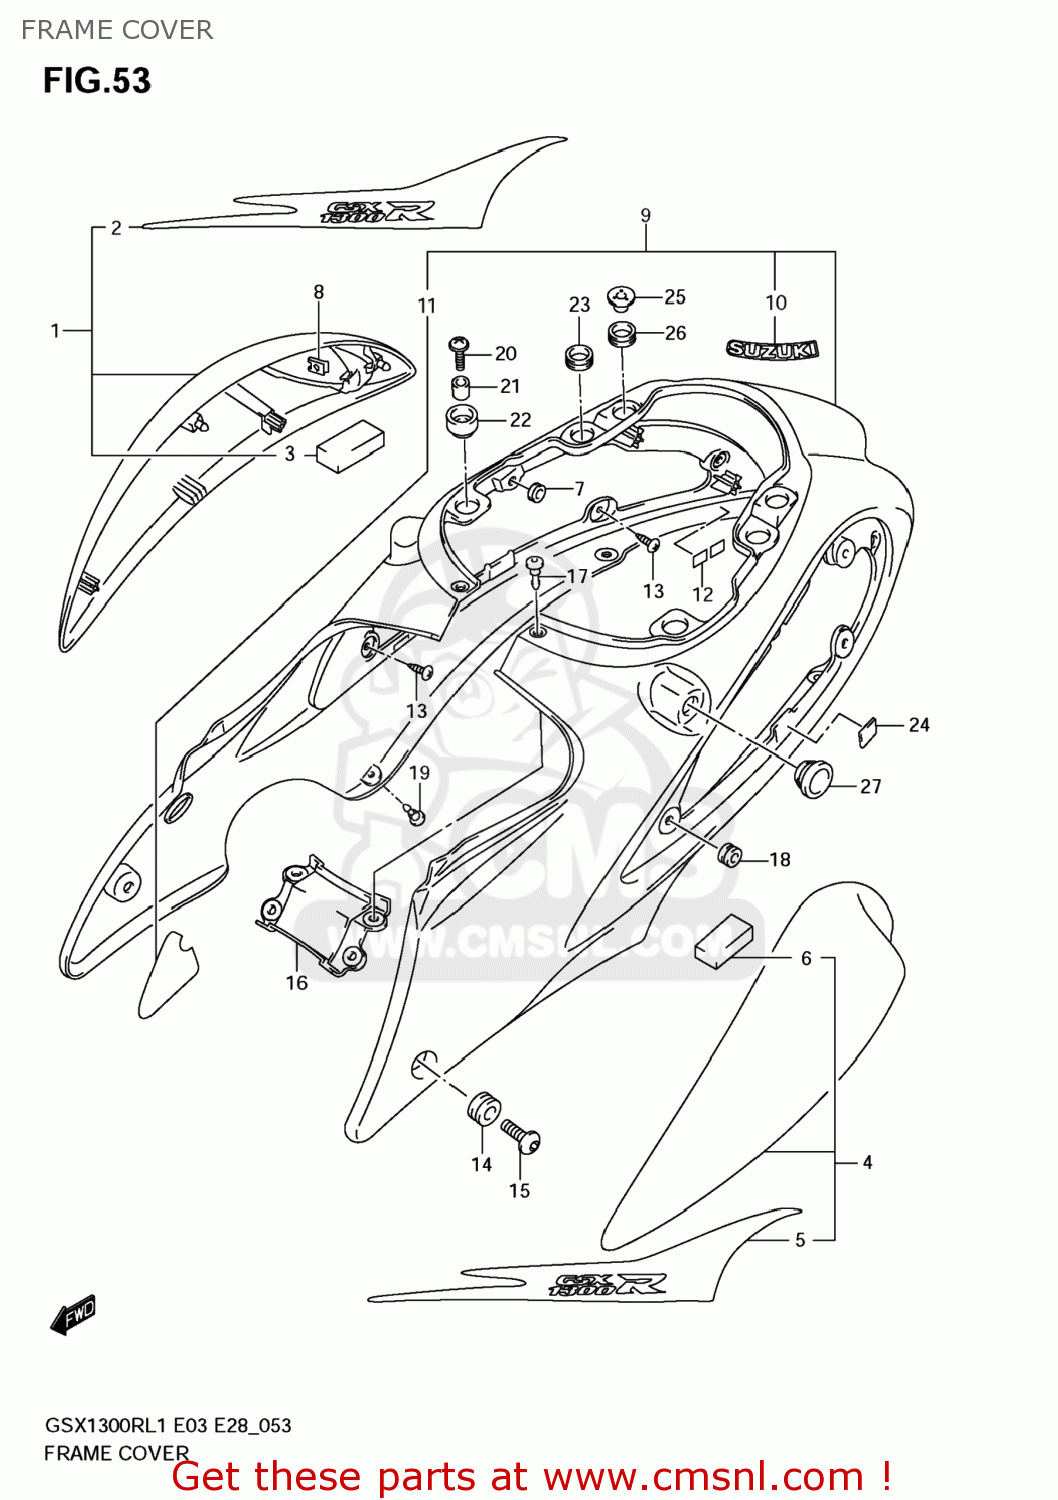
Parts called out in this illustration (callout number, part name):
1	COVER COMP,FRA
2	TAPE,FRAME COVER,R
3	CUSHION,FRAME COVER
4	COVER COMP,FRA
5	TAPE,FRAME COVER,L
6	CUSHION,FRAME COVER
7	CUSHION
8	NUT
9	COVER,FRAME CTR
10	EMBLEM,SUZUKI
11	TAPE,CTR
12	CUSHION,SEAT TAIL COVER LWR RR
13	SCREW(5X15)
14	CUSHION
15	SCREW(6X20)
16	LID,FRAME COVER CTR
17	CLIP(BLACK)
18	CUSHION
19	CLIP
20	SCREW(6X20)
21	SPACER(6.5X10X11)
22	CUSHION,SEAT TAIL COVER CTR
23	CUSHION,FRAME COVER UPR RR
24	PROTECTOR(170X95X3.0)
25	WASHER,FRAME COVER
26	CUSHION,FRAME COVER UPR RR RR
27	CUSHION,FRAME COVER CTR
